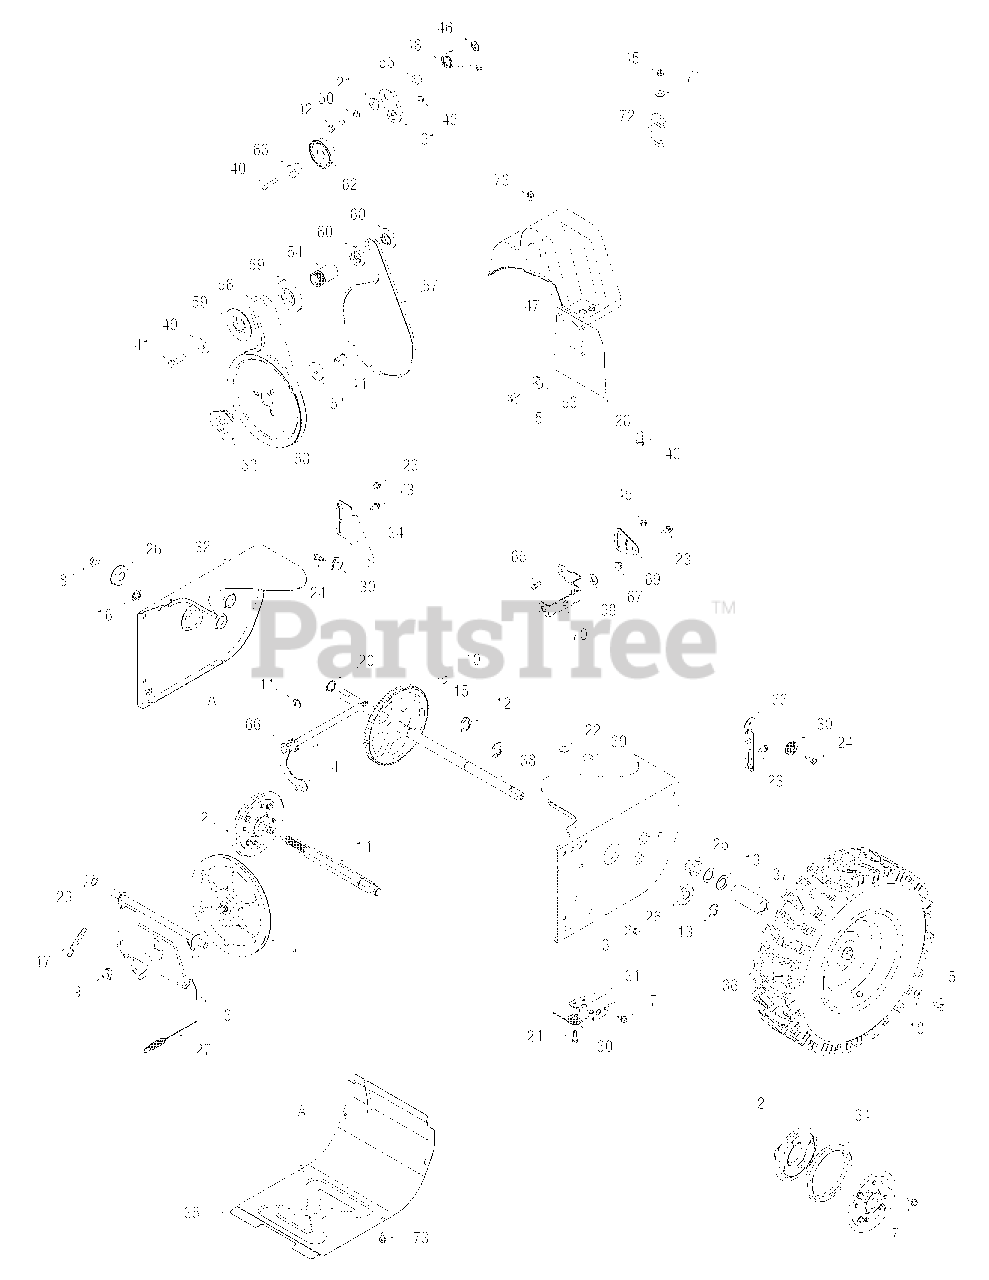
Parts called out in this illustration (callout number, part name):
1	Disc Assembly, Friction Wheel
2	Friction Wheel Assembly, 5.5 OD
4	Shift Assembly, Rod
5	Hex Screw, 5/16-24, .750, Gr5
6	Screw, 1/4-20, 1.000
7	Screw, 1/4-14 x .625
8	Nut, Flange Lock, 3/8-16, Nylon
9	Nut, Jam Lock, 5/8-18, Gr5, Nylon
10	Key, Hi Pro, 3/16 x 3/4 Dia.
11	E-ring, .500 Dia.
12	E-ring, Retaining, .875 Dia.
13	E-ring, .750 Dia.
14	Hex Shaft, .8125, 7-Tooth
15	Gear, 80-Tooth
16	Speed Nut, .500
17	Extension Spring
18	Washer, Bell, .340 x .872 x .060
19	Washer, Flat, .793 x 1.24 x .060
20	Washer, Flat, .75 x 1.00 x .060
21	Spacer, Shldr., .3175 ID x .500 x .094
22	Plug, 1/2 ID
23	Screw, Shoulder, .37 x .105, 1/4-20
24	Screw, 1/4-28, .375
25	Bearing, Hex Flange x .75 ID
26	Bearing, Ball, 17 x 40 x 12
27	Clutch Cable, Wheel, 44.95"
29	Spacer, .508 ID x .75 OD x .68
30	Roller, Cable
37	Spacer, 1.25 x .75 x 3.0
38	Axle, .75 x 22"
39	Plug, 3/8 ID
40	Hex Screw, 1/4-20, 1.25, Gr5
41	Hex Screw, 3/8-24, 1.25, Gr8
42	Hex Screw, 5/16-24, 1.25, Gr5
43	Screw, Sems, 3/8-16, 1.00
44	Hex Screw, 5/16-24, .875, Gr8
45	Nut, Flange Lock, 1/4-20, Nylon
46	Nut, Push-on, .25 Dia.
47	Cover, Belt
48	Spring, Torsion, .850 ID x .354
49	Washer, Flat, .406 x 1.25 x .157
50	Washer, Lock .3125
51	Washer, Flat, .34 x 1.50 x .150
52	Pulley, Adapter, .75 Dia.
53	Spacer, Shoulder
54	Spacer, .875 ID x 1.185 OD
55	Spacer, .340 x .750 x .360
56	Belt, Auger Drive
57	Belt, Wheel Drive
58	Pulley, Auger Drive, 8.1 x .5
59	Pulley, Half, V x 2.600 OD
60	Pulley, Half, 3/8-V x 1.7160 OD
61	Idler Bracket, Wheel Drive
62	Idler Pulley Assembly
63	Spacer, Shoulder, .26 x .79 x .538
64	Rubber, Friction Wheel, 5.5 OD
65	Hex Screw, 1/4-20, .620, Gr5
66	Spring, Torsion, .750 ID x .968
67	Nut, Flange Lock, 5/16-18, Nylon
68	Washer, Flat, .469 x .875 x .105
71	Washer, Flat, .28 x .74 x .063
72	Cable Control Wire
73	Screw, 1/4-20 x .625
